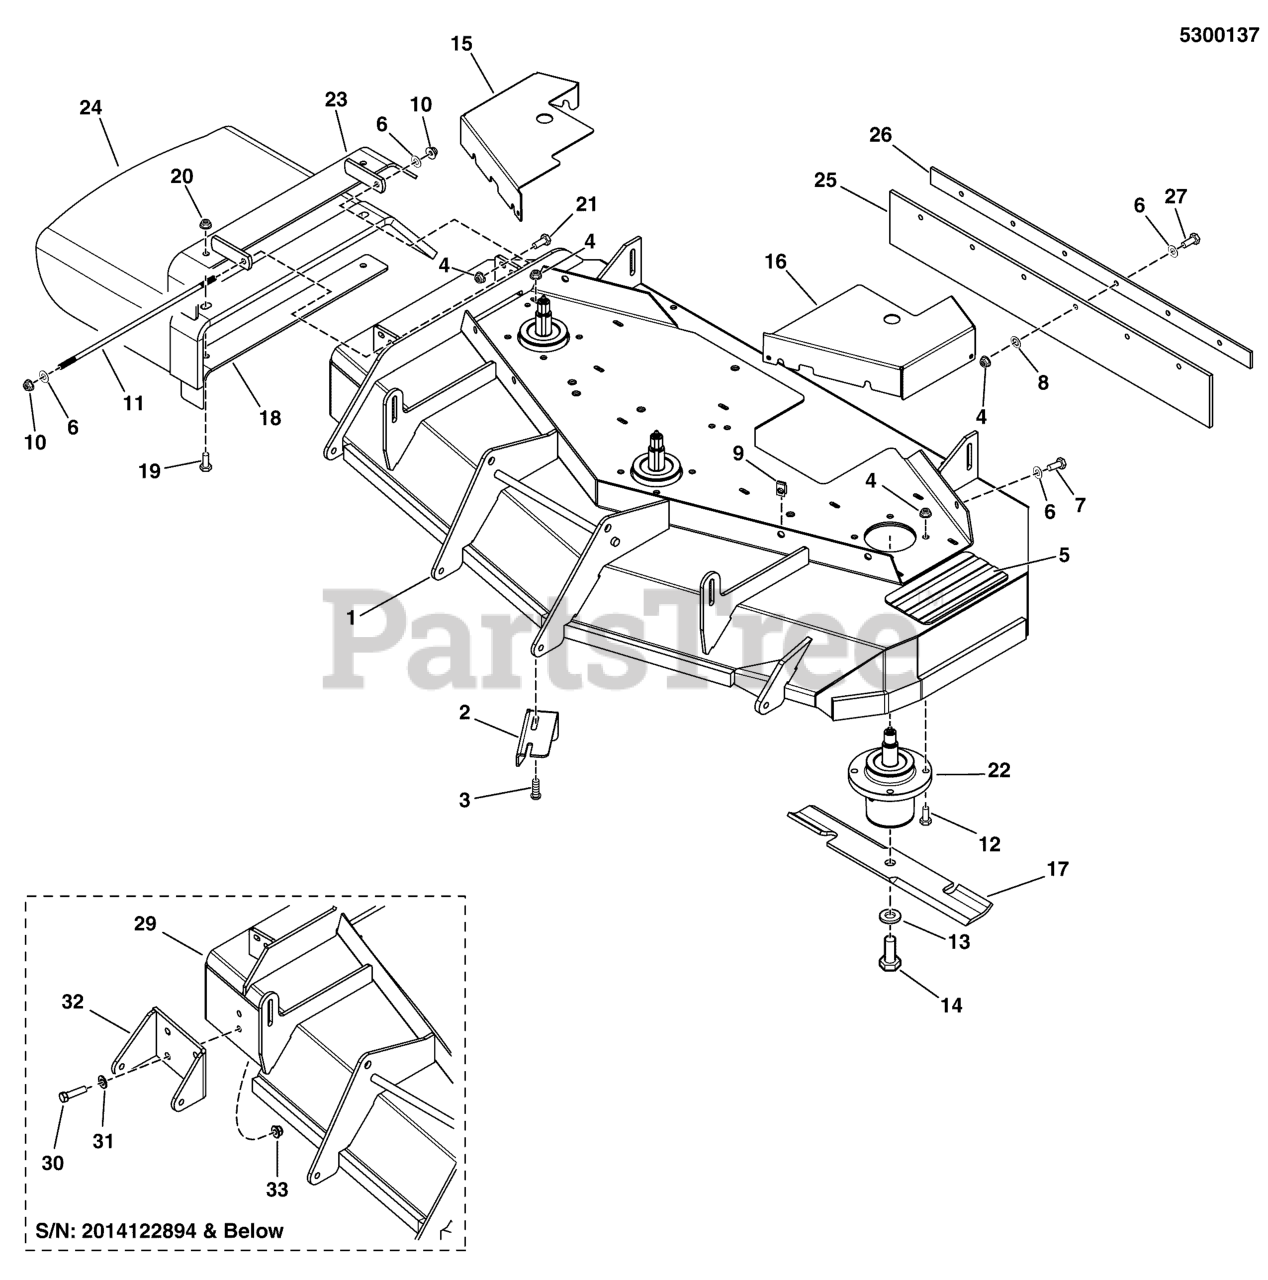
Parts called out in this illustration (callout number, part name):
1	DECK SHELL W/ DECALS, IS1500Z, 48" iCD
2	PLATE, DEFLECTOR - BLK
3	BOLT, 5/16-18 X 3/4, CARRIAGE
4	NUT, 5/16-18 HEX NYLOCK FLANGE
5	SAFETY WALK, 4.00 X 7.50
6	WASHER, 5/16" SAE
7	BOLT, 5/16-18 X 3/4 GD5
8	5/16 PUSH-ON NUT RETAINER, STL, CZ
9	BODY CLIP, 5/16-18-7GA MATERIAL
10	NUT, 5/16-24 HEX NYLON LOCK
11	ROD, 5/16 X 13.75, TBE, CZ
12	BOLT, 5/16-18 X 1 1/4 FLANGE
13	WASHER, 5/8 GRADE 8, YZ
14	BOLT, 5/8-11 X 1-3/4 GD8
15	GUARD, DECK, RH - RED
16	GUARD, DECK, LH - RED
17	BLADES, SET OF THREE (3); 16.25 X.25 X 2.5, 1 X 3.5
18	SUPPORT, DISCHARGE CHUTE, 44/48/52 - BLK
19	BOLT, 3/8-16 X 1-1/2" GD5 CZ
20	NUT, 3/8-16 HEX NYLOCK FLANGE
21	BOLT, 5/16-18 X 1, CARRIAGE
22	ASSM, SPINDLE, LOW PROFILE
23	WELD, FRAME, CHUTE, 48/52 -BLK
24	CHUTE, DISCHARGE, BEND RUBBER, 44/48/52
25	FLAP, RUBBER, 48"
26	PLATE, SUPPORT, 48 - BLK
27	BOLT, 5/16-18 X 1 GD5 YZ
28	KIT, DISCHARGE CHUTE
29	DECK SHELL W/ DECALS, 48 - IS1500Z
30	BOLT, 3/8-16 X 1-1/2" GD5 CZ
31	WASHER, 3/8 SAE
32	WELD, BRACKET, ANTI SCALP - RED
33	NUT, 3/8-16 HEX NYLOCK FLANGE
